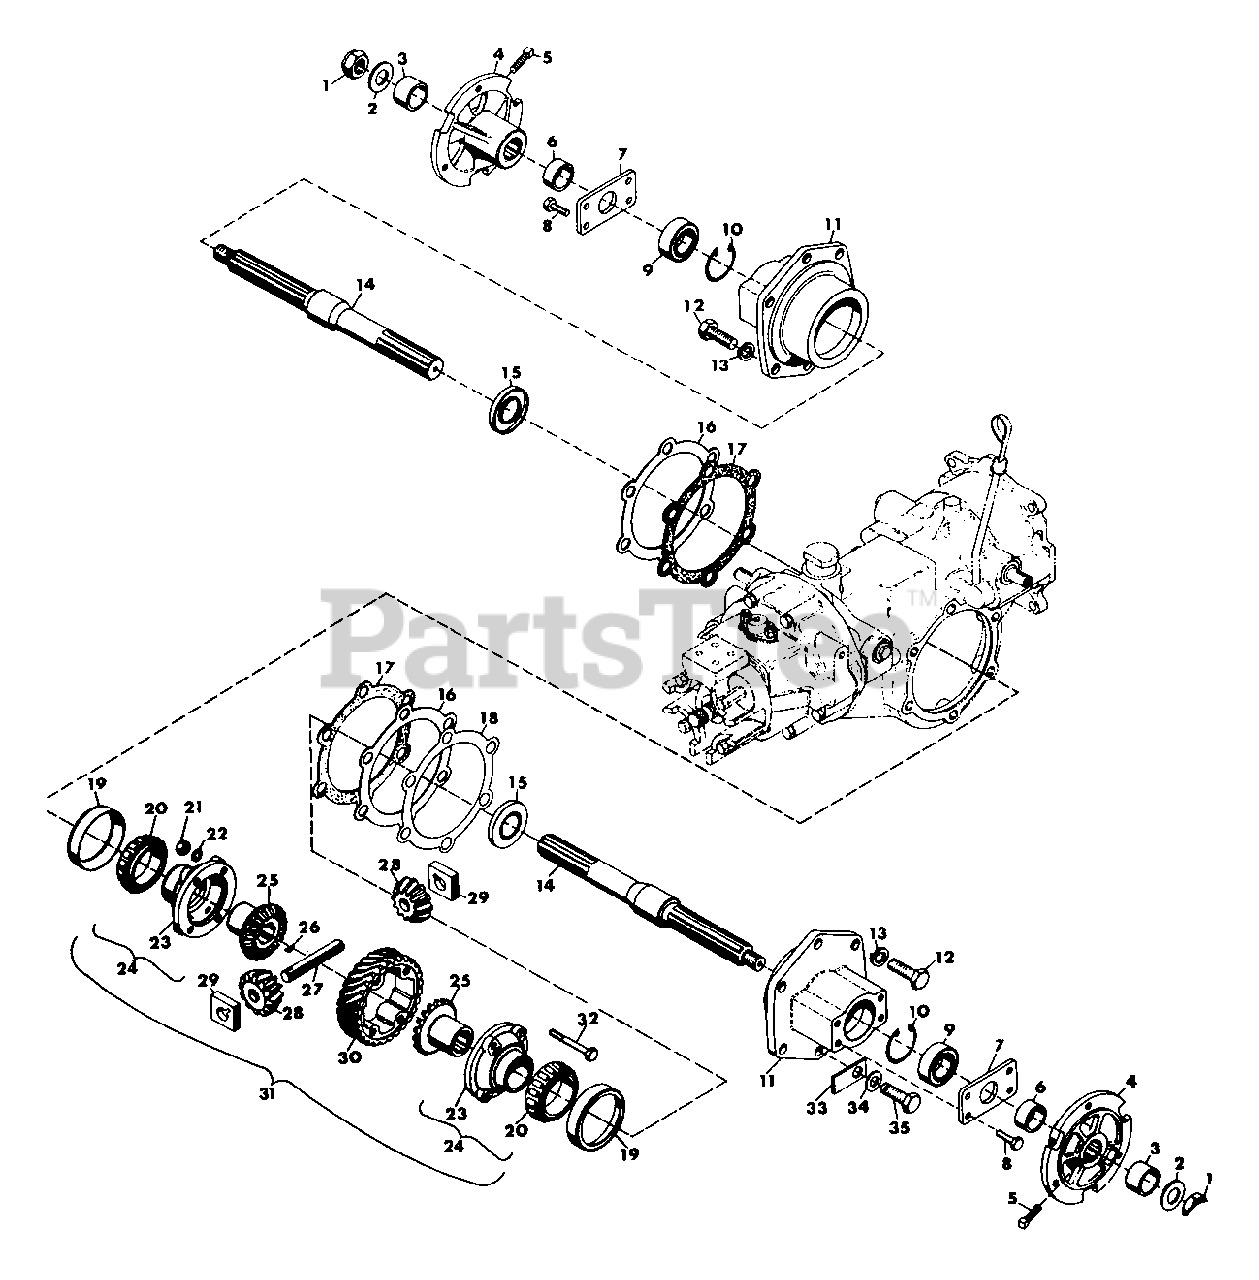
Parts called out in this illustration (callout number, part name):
1	Nut,Hex 3/4-10 Light Thin
2	Washer, Flat .812x1.469x.134
3	Spacer
4	Hub, Wheel
5	Screw, Set 7/16-14x1.00 SQHCP
6	Spacer
7	Plate, End
8	Bolt, Hex 3/8-16X.750
9	Bearing, Ball 1.00x2.000x.562
10	Ring, Retaining 2.000 Bore
11	Housing, Axle
12	Bolt, Hex 1/2-13x1.00
13	Washer, Lock 1/2 Reg.
14	Axle, Straight
15	Seal, Oil 1.188x2.00x.250
16	Shim, Axle Housing .005
17	Gasket, Axle Housing
18	Shim, Axle Housing .020
19	Cup, Roller Bearing
20	Cone, Roller Bearing
21	Nut, Hex 5/16-24
22	Washer, Lock 5/16 Int. Tooth
23	Housing, Differential
24	Assembly, Differential Housing
25	Gear, Differential Bevel
26	Key, Woodruff .125x.375 Hard
27	Pin, Spider Pinion
28	Gear, Spider Bevel
29	Block, Drive
30	Gear, 6 Lead Worm
31	Assembly, Diff. Std. 6 Lead
32	Bolt, Hex 5/16-24x2.75
33	Washer, Oil Drain
34	Washer, Flat .531x1.062x.095
35	Bolt, Hex 1/2-13x1 Nylon Insert
